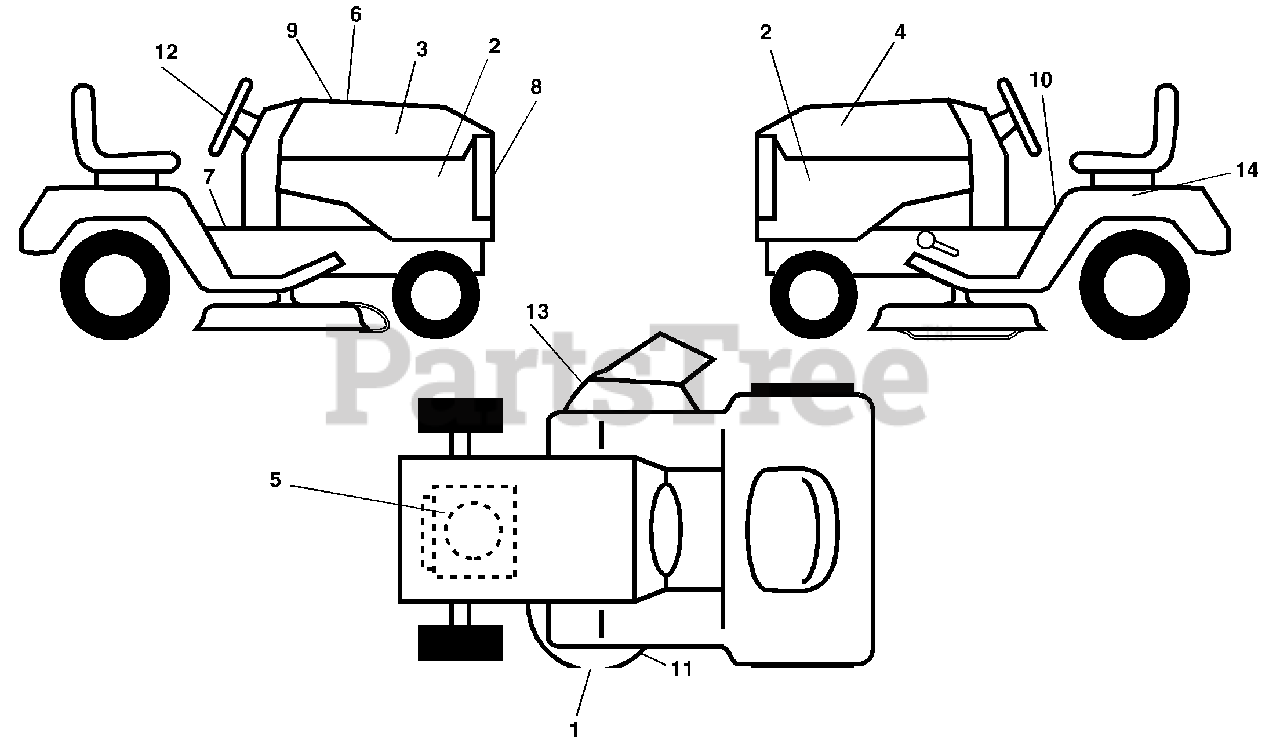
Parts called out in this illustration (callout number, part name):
1	Decal Deck Hvy Duty
2	Decal Panel Side
3	Decal Hood RH
4	Decal Hood LH
5	Decal HP Engine
6	Decal Hood Cust. Resp.
7	Decal Operator
8	Decal Dash
9	Decal Replacement
10	Decal Fender Danger
11	Decal V-Belt Sch.
12	Decal Wheel Steering
13	Decal Warning
14	Decal Bat Dan/Psn
